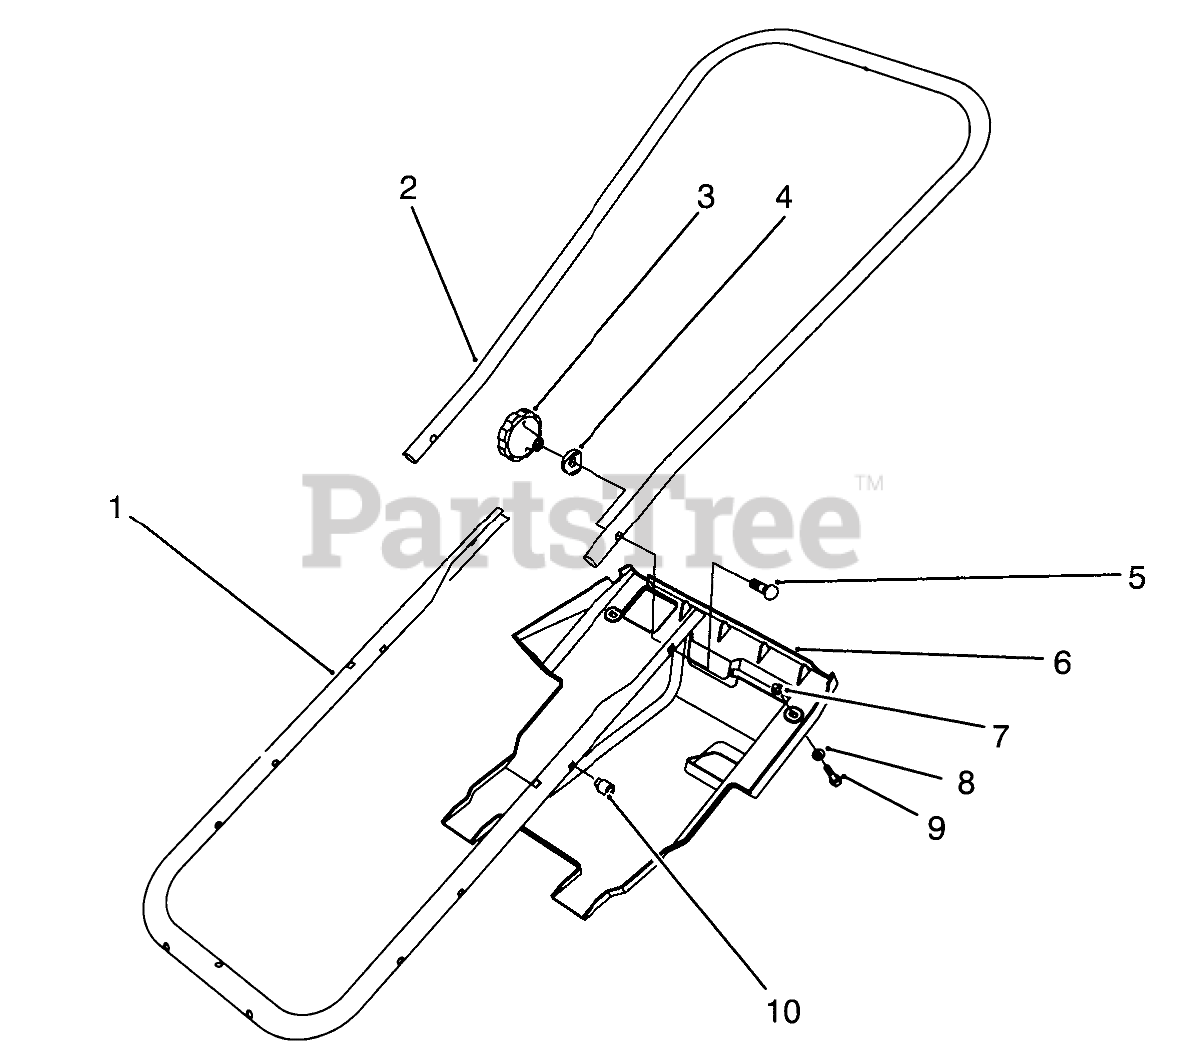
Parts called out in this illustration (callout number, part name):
1	Tube-Frame
2	Handle-Upper
4	WASHER-CURVED
5	SCREW-HANDLE
6	SHROUD
7	Nut-Push
8	WASHER-FLAT
9	SCREW-HWHTF
10	NUT-EXPANSION
